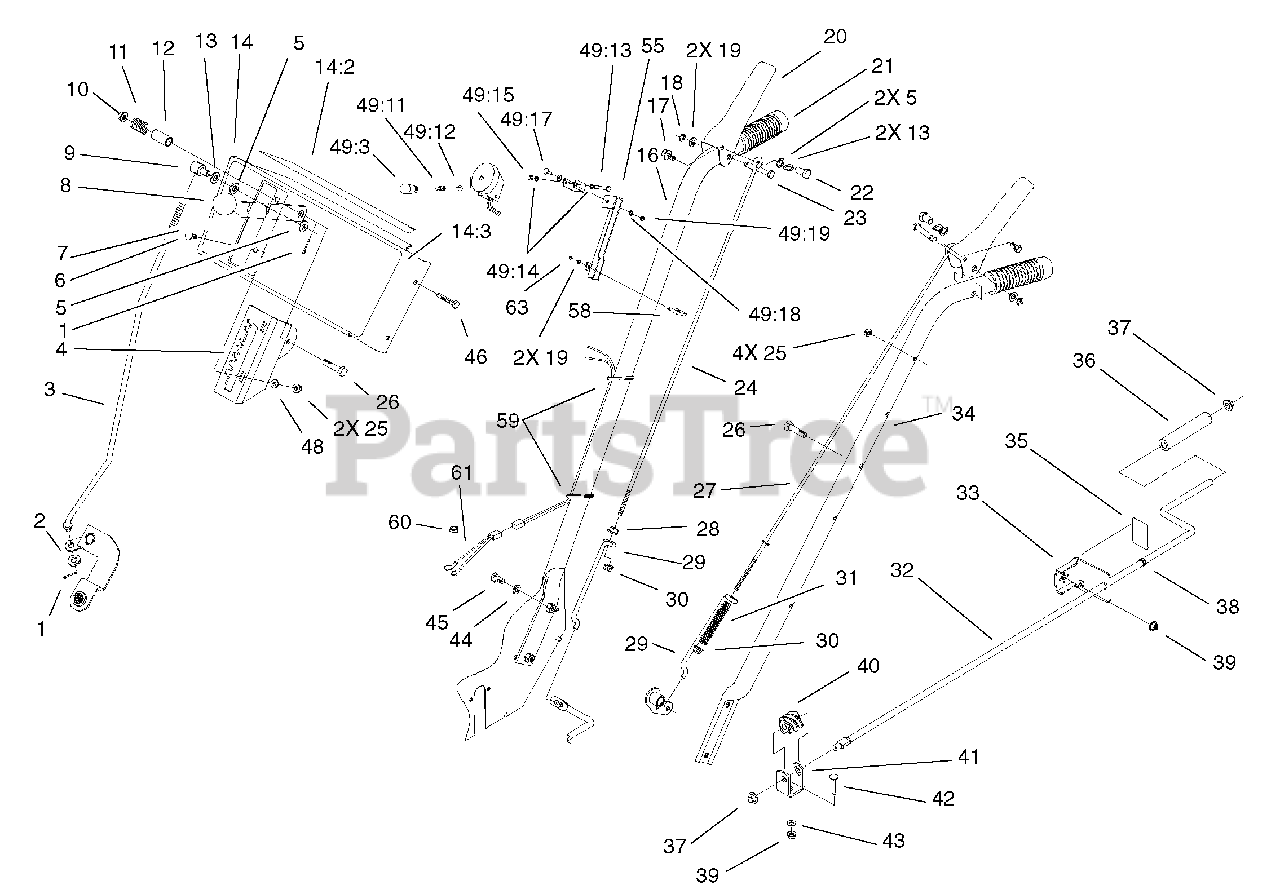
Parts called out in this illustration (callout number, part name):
1	Pin-Cotter
2	Washer-Flat
3	Rod-Shift
4	Mount-Speed Selector
5	Washer-Flat
6	Screw-CARR
7	Selector-Speed
9	Trunion
13	Washer-Spring
14	Control Panel ASM
14:2	Decal-Escutcheon Back
14:3	Decal-Control Panel
16	Handle-Right
17	Screw-HHF
18	Ring-Clip
19	Washer-Flat
20	Handle-Control
21	Grip-Handle
22	Post-Linkage Mounting
23	Pin-Lever, Control
24	Rod-Upper Engage Auger
25	Nut-Lock, NI
26	Screw-HH
27	Rod-Upper Traction
29	Rod-Lower Traction
32	Rod-Control, Chute
33	Bracket-Rod, Chute
34	Left Handle
35	Decal-Chute Direction
36	Grip-Chute Control
37	Retainer-Push On
38	Bushing
39	Nut-Lock, NI
40	Gear-Worm, Chute
41	Bracket-Worm
42	Screw-CARR
43	Washer-Lock
44	Washer-Belleville
45	Screw-HWH
46	Screw-HH
48	Washer-Flat
49:3	Beam-Sealed
49:11	Switch ASM
49:12	Boot-Switch
49:13	Screw-HH
49:14	Washer-Lock/Ext
49:17	Screw-CARR
49:18	Washer-Lock
49:19	Nut-Hex
55	Mount-Light
59	Tie-Cable
60	Nut-Hex
61	Wire ASM
63	Nut-Lock, NI
